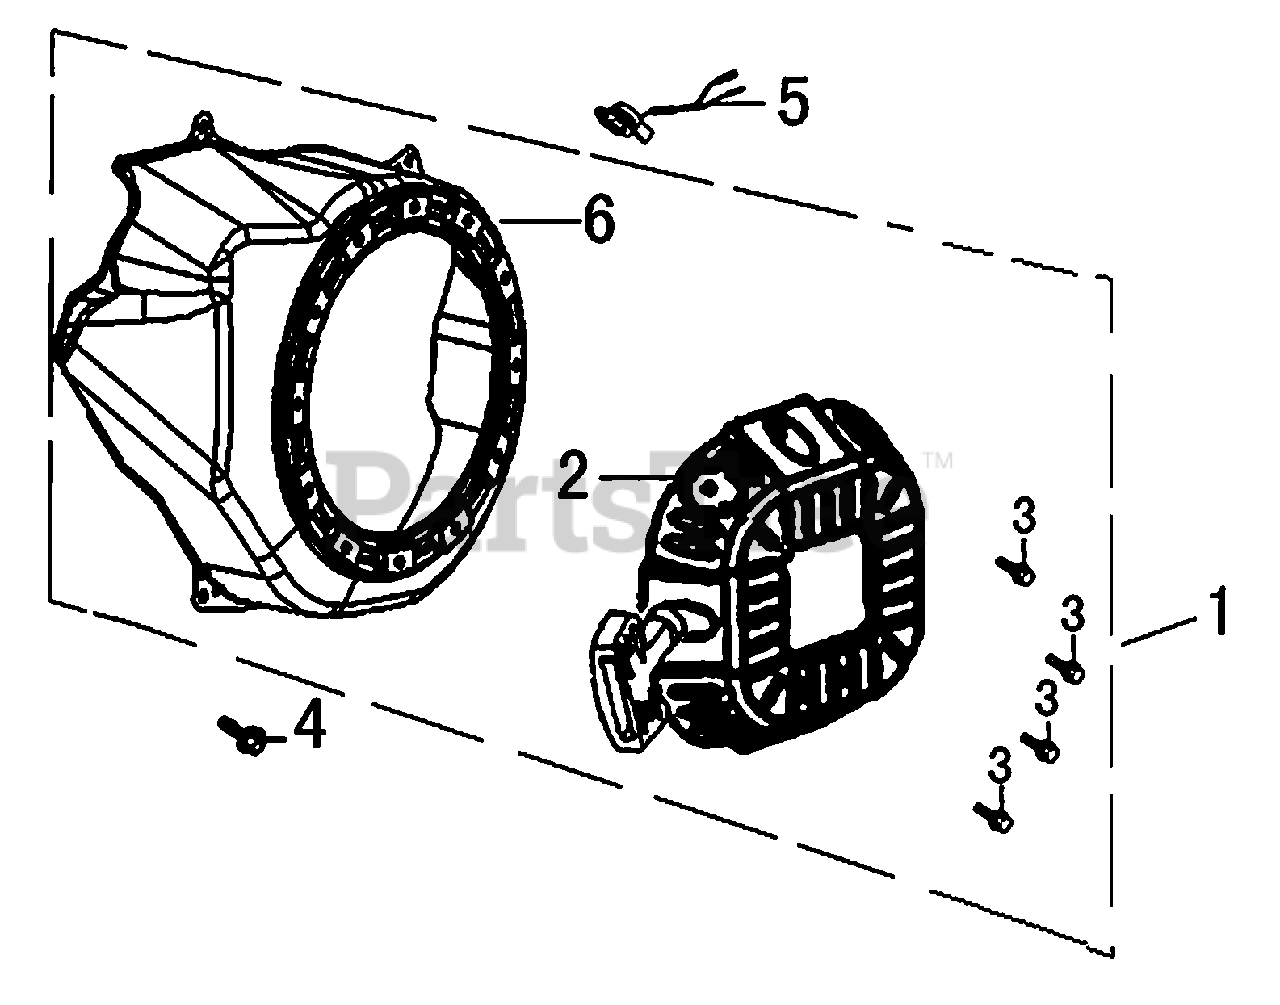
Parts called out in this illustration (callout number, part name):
1	RECOIL STARTER W/HSNG
2	STARTER ASSY. RECOIL
3	BOLT, FLANGE
4	BOLT, FLANGE
5	SWITCH ASSY., ENGINE STOP
6	COVER COMP., FAN
